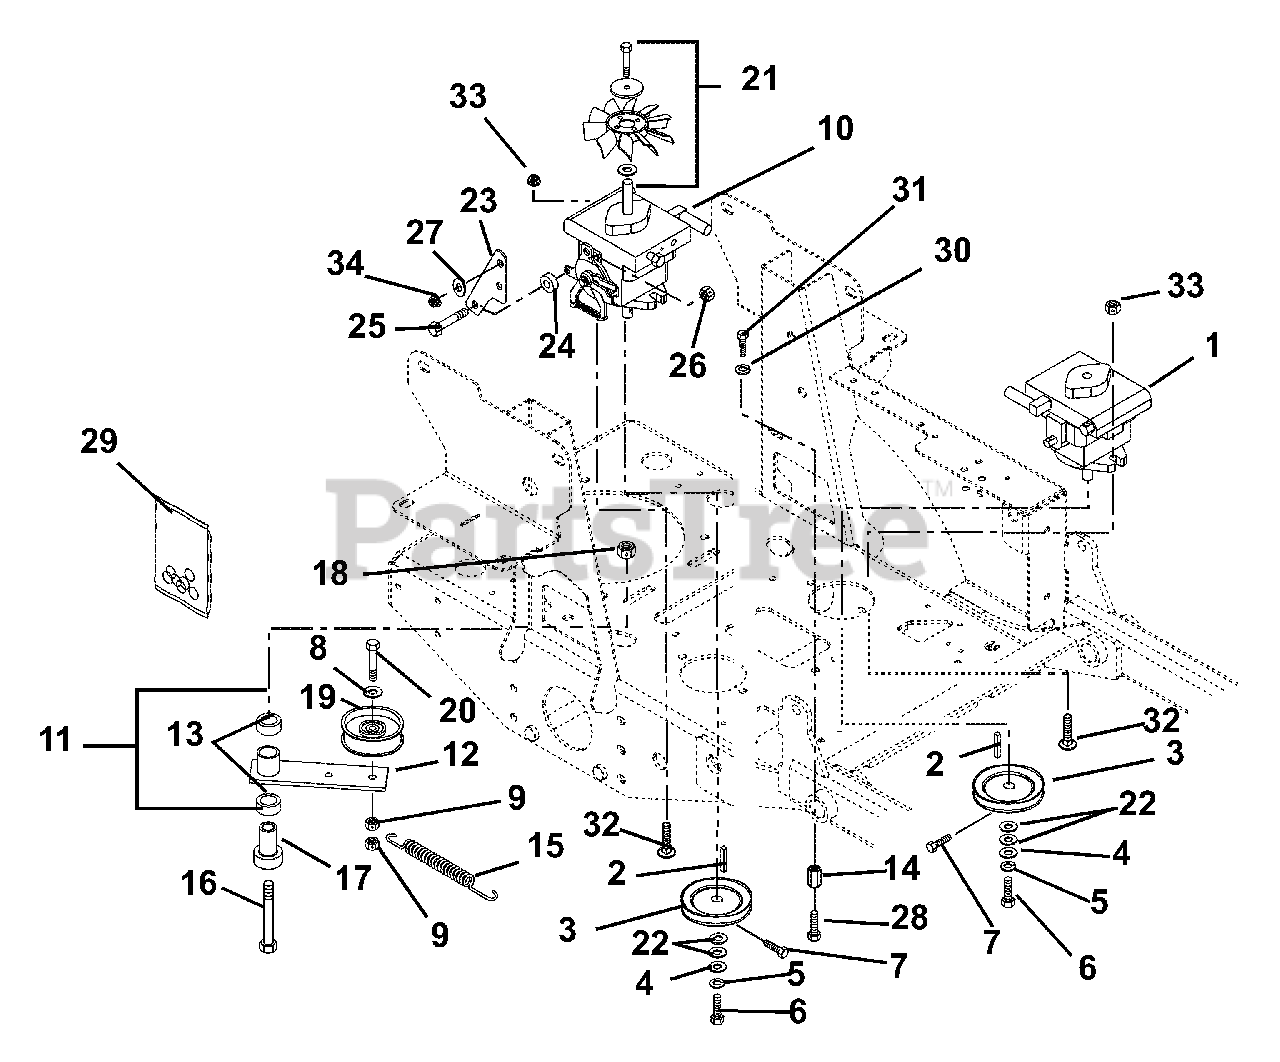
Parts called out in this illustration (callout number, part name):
1	PUMP, HYD BDP-10A (LH)
2	KEY-STR 5MMX25MMX5MM
3	SHEAVE, PUMP .592 X 4.345
4	WSHR-FL-STL .281X1.000X.063
5	@WSHR-LK .25X.062 REG YWZC
6	BLT-HEX M6 X 1.0X12 YWZC
7	BLT-HEX .25-20X.50 GR5 EPOXY
8	WSHR-FL-STL .390X.75X.125 YWZC
9	@NUT-LK-NYL-FLG .38-16 YWZC
10	PUMP, BDP-10A-441 (THRU SHAFT)
11	ASSEMBLY,IDLER ARM GRD.DRIVE
12	WMT, IDLER ARM GROUND DRIVE
13	BRG, 1.00 X 1.12 X .75
14	NUT COUPLING .375-16X1.75
15	SPRING, EXTENSION
16	@BLT-HEX .50-13X3.50 GR5 YWZC
17	BEARING, PEDESTAL
18	@NUT-LK-NYL-FLG .50-13 YWZC
19	IDLER, FLAT 4.00X1.06
20	@BLT-HEX .38-16X2.25 GR5 YWZC
21	FAN, COOLING
22	@WSHR-FL-STL.656X1.31X.095 YWZ
23	BRACKET, RTN/DAMPER
24	SPACER .344X1.000X.375
25	@BLT-HEX .31-18X1.25 GR5 YWZC
26	@NUT-LK-NYL-FLG .31-18 YWZC
27	@WSHR-FL-STL.344X.688X.065YWZC
28	@BLT-HEX .38-16X1.50 GR5 YWZC
29	KIT, PUMP SEAL
30	@WSHR-LK .38X.094 REG YWZC
31	@BLT-HEX .38-16X.75 GR5 YWZC
32	@BLT-RDHDSQNK .44-14X1.50 G5YZ
33	NUT-LK-NYL-FLG .44-14 YWZC
34	@NUT-LK-NYL M8-1.25 YWZC
